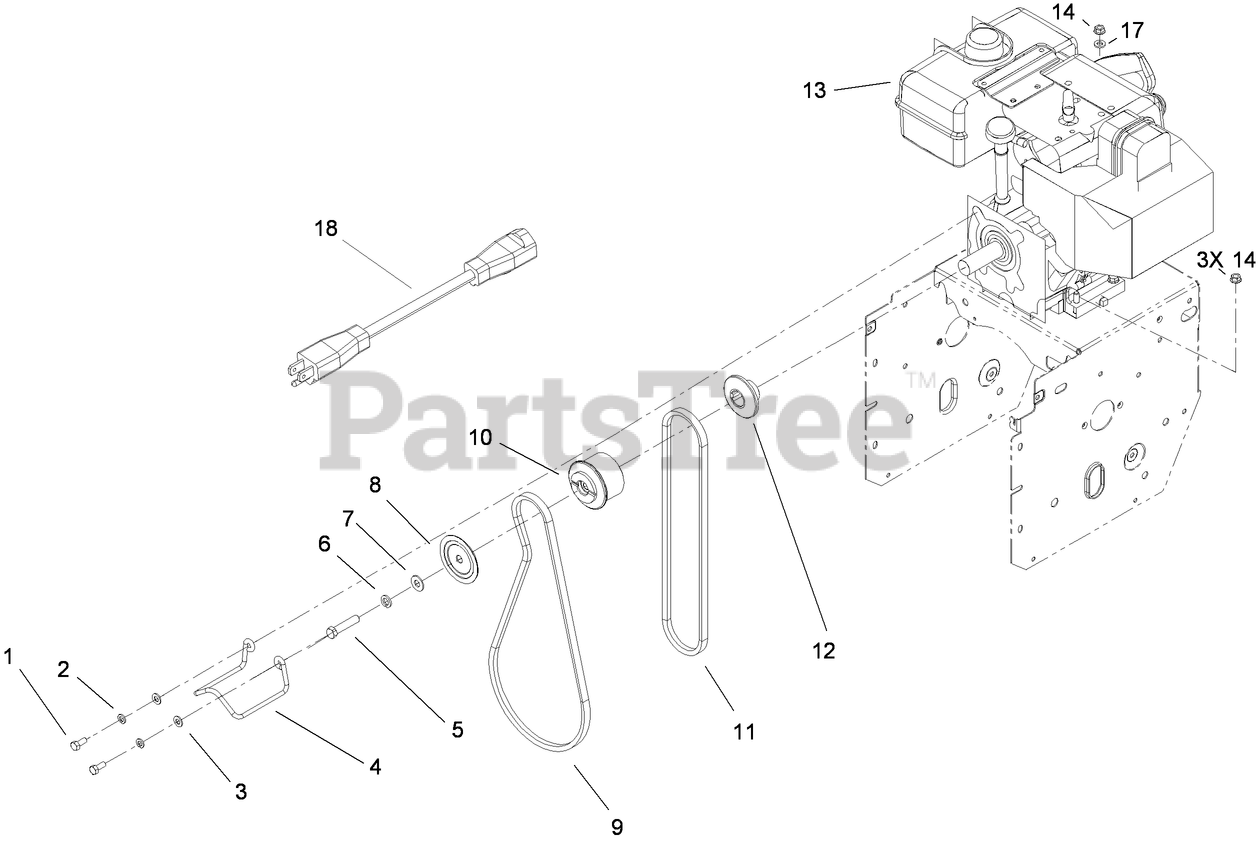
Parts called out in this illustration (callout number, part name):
1	SCREW-HH
2	WASHER-LOCK
3	WASHER-PLAIN
5	SCREW-HH
6	WASHER-LOCK
7	WASHER-FLAT
8	SHEAVE-HALF, IMPELLER
9	BELT-V
10	PULLEY-ENGINE, CENTER
11	V BELT-TRACTION
12	SHEAVE-HALF, TRACTION
13	Loose Parts Package
14	NUT-HF
17	WASHER-FLAT
18	CORD-EXTENSION (only on: 38078)
